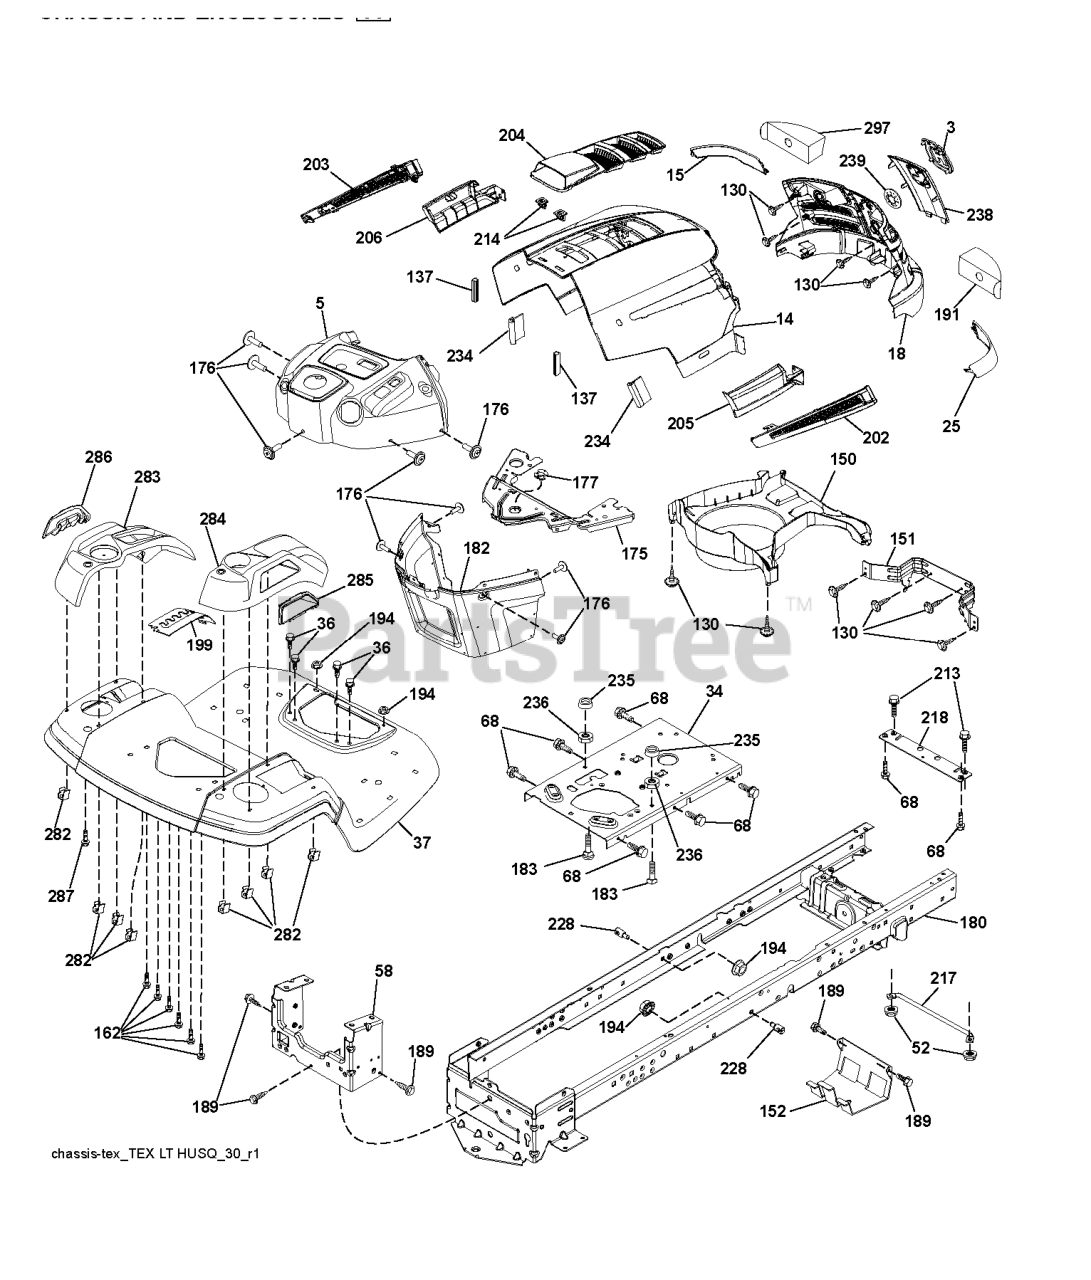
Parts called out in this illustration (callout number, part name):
3	RP LOGO
5	DASH
14	HOOD.HUSQVARNA.LT.ORANGE
15	LENS.HUSQVARNA LT.LH
18	GRILLE.SVC.HUSQVARNA.LT.GREY
25	LENS.HUSQVARNA LT.RH
34	PLATE.ENGINE.WELDED.CHASSIS
36	SCREW 5/16"
37	FENDER.TLT.FS.W/CUPHLD.ORANGE
52	LOCKNUT
58	DRAWBAR UPPER 2PC SMALL FENDER
68	Screw 5/16-18 x 1/2 Hex, Self Tapping 5/16-18 x 1/2
130	SCREW.#10 X 0.750.BOS
137	BUMPER DASH
151	BRACKET PIVOT
152	SHIELD.BROWNING.W/TEX
162	SCREW.HI-LO.CONSOLE
175	CROSSMEMBER
176	SCREW.#10-24X5/8.RN.QU
177	BUSHING STEERING
180	CHASSIS.WLDMNT.14GA.2PC.18".TI
182	DASH.LOWER.PREDATOR LT
183	BOLT.5/16-18X1-1/4 FULL THD
189	SCREW
191	INSERT.REFLECTIVE.RH.
194	NUT LOCK HEX FLANGE 5/16-18
199	PLATE.DECK.LIFT.HUSQ.LT
202	VENT SIDE HOOD LH
203	VENT SIDE HOOD RH
204	VENT TOP HOOD
205	SKIRT SIDE RH
206	SKIRT SIDE LH
213	BOLT
214	CLIP.RETAINER.TINNER.
217	ROD.PIVOT.HOOD
218	X-PIECE.HOOD.STOP.NON/
228	STUD.FASTNER.W/ANTI-ROTATE
234	BUMPER.HOOD.TEX.HUSQVARNA
235	SPACER FENDER
236	NUT.CENTERLOCK.5/16-
238	TRIM
282	CLIP.RETAINER.CONSOLE.LT.HUSQ
283	CONSOLE.DECK.LIFT.HUSQ.N/FR.GR
285	CONSOLE INSERT RH
286	CONSOLE.INSRT.LH.HUSQ.LT.BLACK
287	SCREW 1/4X20
297	INSERT REFLECTIVE
